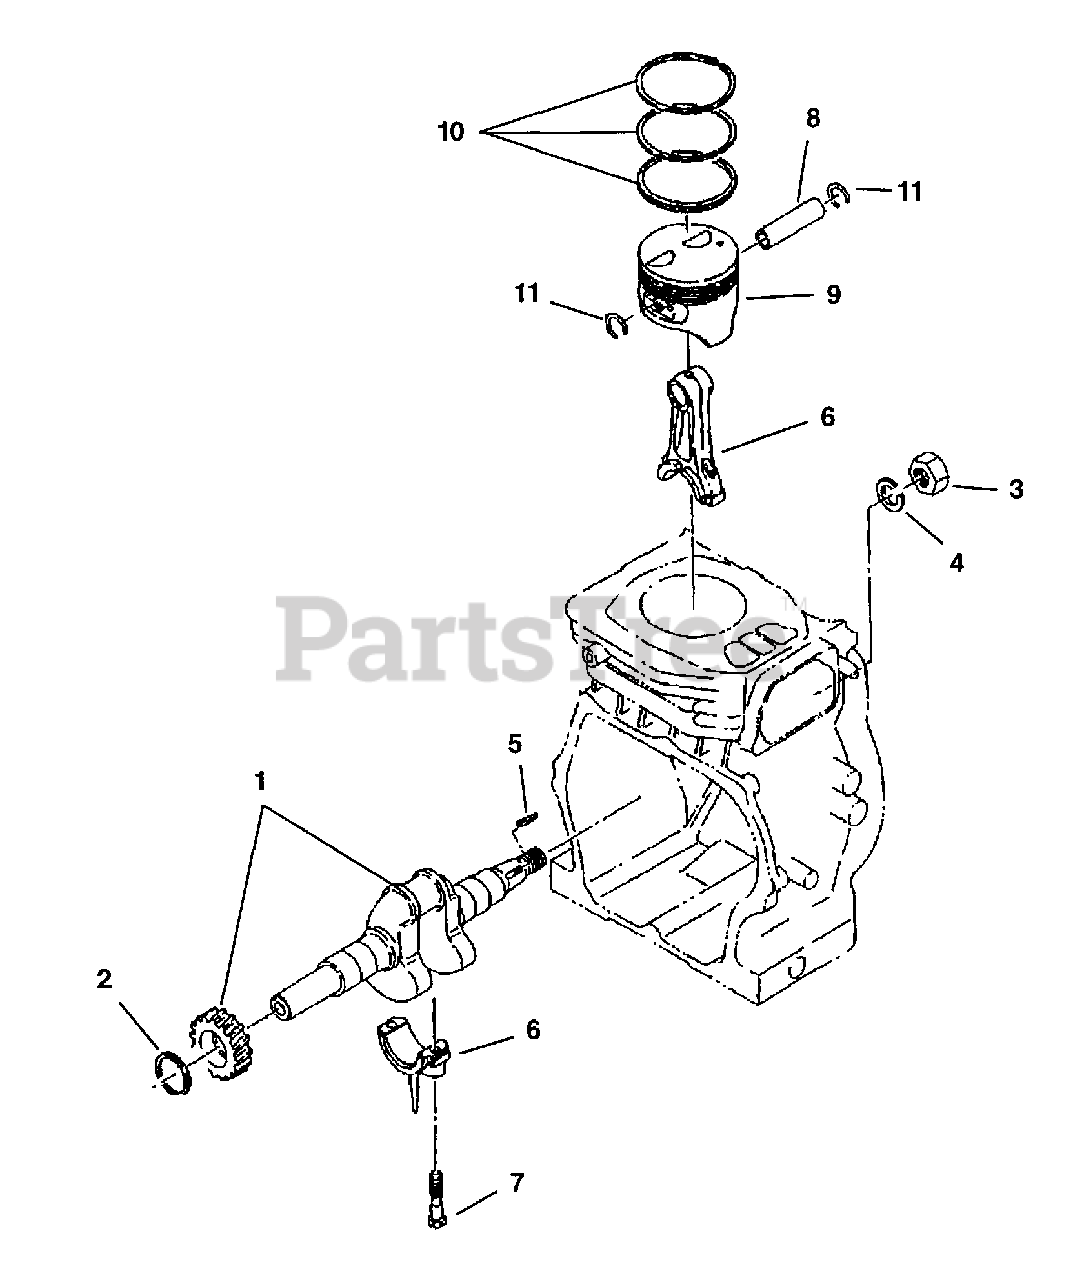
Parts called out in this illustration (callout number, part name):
1	Crankshaft
2	Spacer
3	Nut
4	Spring washer
5	Woodruff key
6	Connecting rod
7	Connecting rod bolt
8	Piston pin
9	Piston
10	Piston ring set
